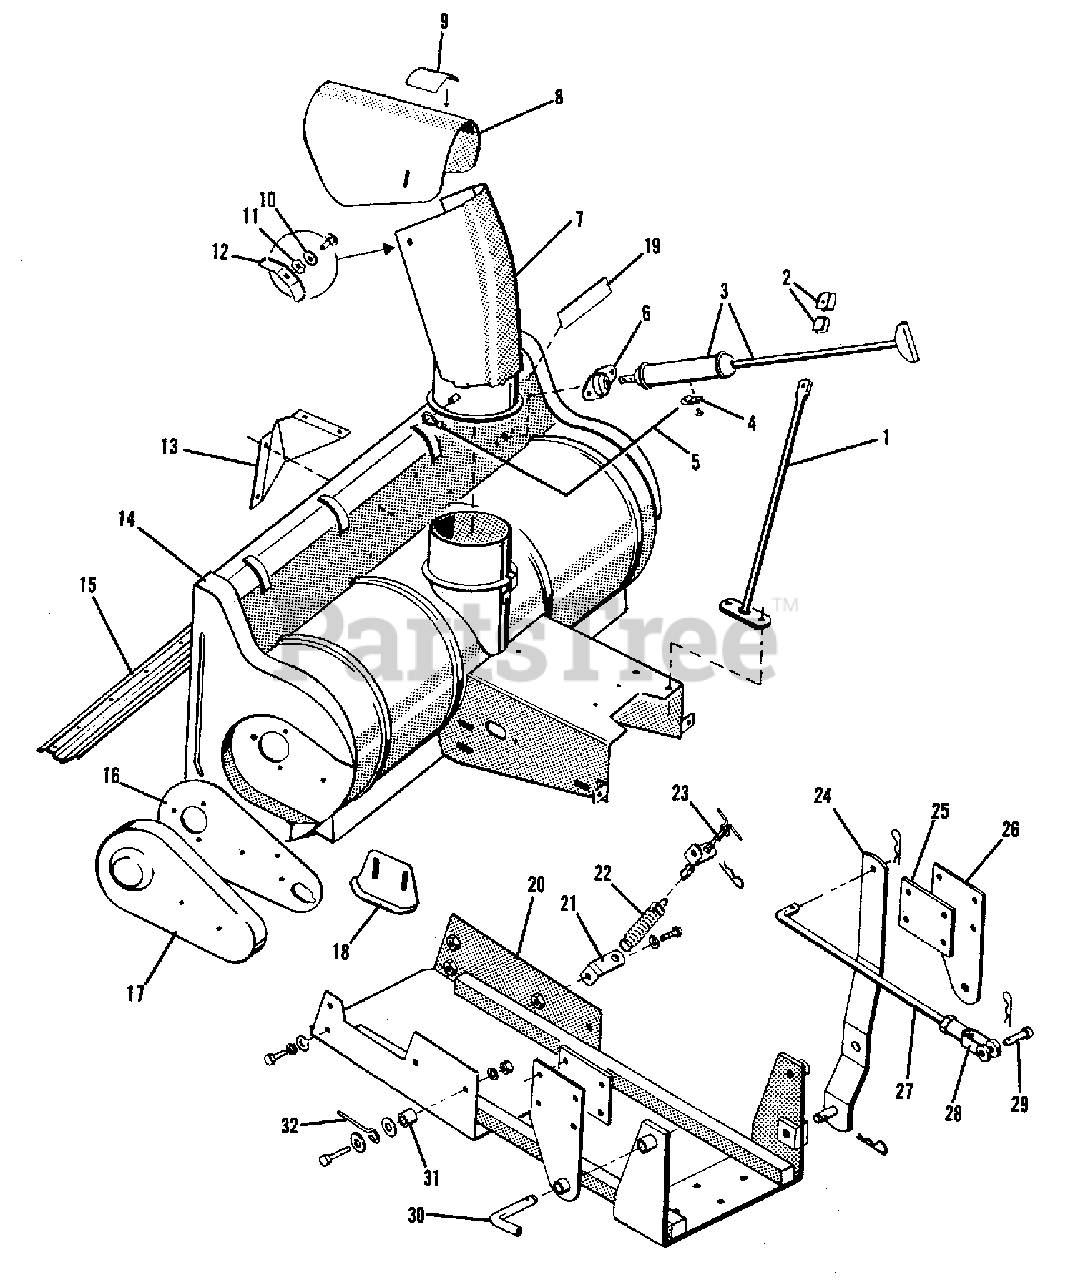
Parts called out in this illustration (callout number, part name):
1	SUPPORT ASSEMBLY, Spout Rod
1	CAPSCREW, 1/4NC x 1
1	LOCKWASHER, 1/4
1	NUT, 1/4NC
2	GUIDE, Control rod
2	LINER, Rod Guide
2	CAPSCREW, 5/16NC x 1-1/4
2	NUT, 5/16NC, Lock
3	LEVER ASSEMBLY, Spout Control
3	PIN, Cotter
4	CLAMP, Cable
4	SCREW, 1/4NC x 3/8 Tapping
5	CABLE ASSEMBLY, Spout Control
5	WASHER, 1/4 Plain
5	LOCKWASHER, 5/16
5	NUT, 5/16NC
6	BEARING ASSEMBLY, Flange
6	CAPSCREW, 1/4NC x 5/8
6	LOCKWASHER, 1/4
6	NUT, 1/4NC
7	SPOUT ASSEMBLY, Thrower
8	EXTENSION, Spout
8	BOLT, 5/16NC x 3/4
8	WASHER, 3/8
9	DECAL, A-C Emblem
10	WASHER, Cup
11	LOCKWASHER, Special, Hex.
12	NUT, Wing
13	DEFLECTOR
13	CAPSCREW, 5/16NC x 5/8
13	LOCKWASHER, 5/16
13	NUT, 5/16NC
14	HOUSING ASSEMBLY, 36" Thrower
15	SCRAPER, Snow, 36" Thrower
15	SCRAPER, Snow, 42" Thrower
15	CAPSCREW, 5/16NC x 5/8
15	CAPSCREW, 1/4NC x 5/8
15	WASHER, 1/4
15	NUT, 1/4NC
15	LOCKWASHER, 1/4
16	PLATE, L.H. Side
17	GUARD, Chain
18	SKID, Shoe
18	BOLT, 3/8NC x 3/4
18	WASHER, 3/8
18	LOCKWASHER, 3/8
18	NUT, 3/8NC
19	DECAL, Safety
20	FRAME ASSEMBLY, Hitch
20	CAPSCREW, 3/8NC x 1
20	WASHER, 3/8
20	LOCKWASHER, 3/8
21	CAPSCREW, 3/8NC x 1
21	LOCKWASHER, 3/8
21	CAPSCREW, 5/16NC x 1-1/4
21	WASHER, 5/16
21	LOCKWASHER, 5/16
21	NUT, 5/16NC
22	SPRING, Extension
23	CHAIN ASSEMBLY, Lift
23	PIN, Quick
24	LEVER ASSEMBLY, Lift
24	PIN, Quick
25	PLATE, Threaded Nut
26	HITCH ASSEMBLY, L.H.
26	HITCH ASSEMBLY, R.H
26	CAPSCREW, 3/8NC x 1
26	LOCKWASHER, 3/8
27	ROD, Lift
27	NUT, 1/2NF, Jam
27	PIN, Quick
28	CLEVIS, Lift Rod
29	PIN, round head
29	PIN, Quick
30	PIN, Hitch
30	PIN, Quick
31	CAPSCREW, 1/2NC x 2
31	WASHER, 17/32 x 1-1/4 x 16 Ga.
31	LOCKWASHER, 1/2
31	NUT, 1/2NC
32	NUT, 5/16NC
